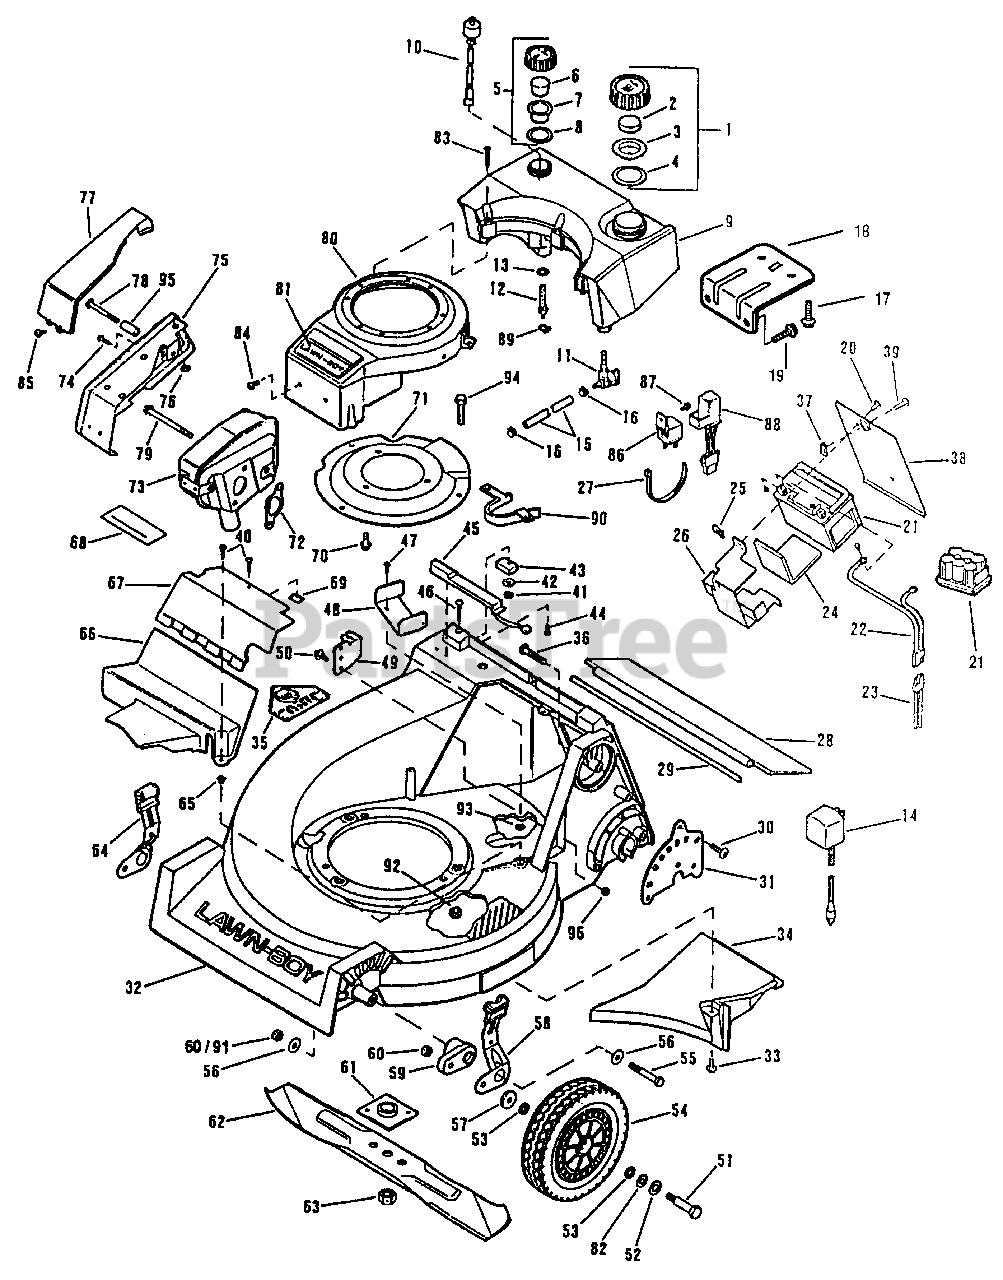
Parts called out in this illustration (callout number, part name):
1	Fuel Cap Assembly
2	Baffle
3	Cover
4	Gasket
5	Oil Cap Assembly
6	Filter
7	Cover
8	Gasket
9	Fuel/Oil Tank Assy (EMRB)
9	Fuel/Oil Tank Assy (EMRC & D)
10	Switch-Low Oil (EMRB)
10	Switch-Low Oil (EMRC & D)
11	Fuel Shut-Off Valve
12	Oil Fitting Assembly
13	O-Ring
14	Battery Charger
15	Fuel Line
16	Clamp-Fuel Line
17	Screw-Fuel Tank Mounting
18	Fuel Tank Bracket
19	Bolt-Bracket and Starter to Block
20	Screw-Battery Bracket to Door
21	Battery Pack
22	Battery Wire Ham (EMRC & D)
23	Wire Harness, Lower
24	Pad-Battery (EMRB)
24	Pad-Battery (EMRC & D)
25	Speednut
26	Battery Bracket
27	Tie Strap (EMRB)
27	Tie Strap (EMRC & D)
28	Trailing Shield
29	Rod-Trailing Shield
30	Screw-Plate to Housing
31	Height Adjust Plate
32	Housing Assy (EMRB & D)
32	Housing Assly (EMRC)
33	Screw-Baffle to Housing
34	Baffle
35	Decal-Blade Contact Warning
36	Handle Mounting Bolt
37	Speednut
38	Access Door
39	Screw
40	Screw (EMRB)
41	Nut
42	Lockwasher
43	Magnet Assembly
44	Screw (EMRB & C)
45	Switch-Bag Lock (EMRB)
46	Screw (EMRB)
47	Screw
48	Belt Guide
49	Cable Anchor
50	Screw
51	Shoulder Bolt-Wheel
52	Washer-Wheel Bolt
53	Felt Washer
54	Wheel and Tire Assembly
55	Screw
56	Washer
57	Washer
58	Knob and Spring Assembly-L.H.
59	Front Height Adj Arm (EMRB & D)
60	Nut (EMRB)
61	Collar and Plate Assembly
62	21" Blade
63	Nut-Blade
64	Knob and Spring Assembly-R.H.
65	Grommet
66	Lower Drive Cover
67	Upper Drive Cover w/Decal
68	Decal-Warning
69	Speednut
70	Screw-Mounting Plate to Engine
71	Engine Mounting Plate
72	Exhaust Gasket
73	Muffler
74	Screw-Muffler Guard
75	Muffler Guard Assembly
76	Pushnut
77	Muffler Cover
78	Screw-Muffler Guard
79	Screw-Muffler
80	Shroud and Applique Assembly
81	Applique
82	Washer-Shim
83	Screw-Fuel Tank
84	Screw-Shroud
85	Screw-Muffler Guard
86	Starter Relay
87	Screw-Relay to Battery Bracket
88	Electronic Cup Assembly
89	Clamp-Oil Hose
90	Belt Snubber
91	Nut (EMRC & D)
92	Locknut-Mting Plate to Housing
93	Locknut-Belt Guide to Housing
94	Screw-Mting Plate to Housing
95	Spacer-Muffler Guard
96	Nut-Cable Anchor to Housing
